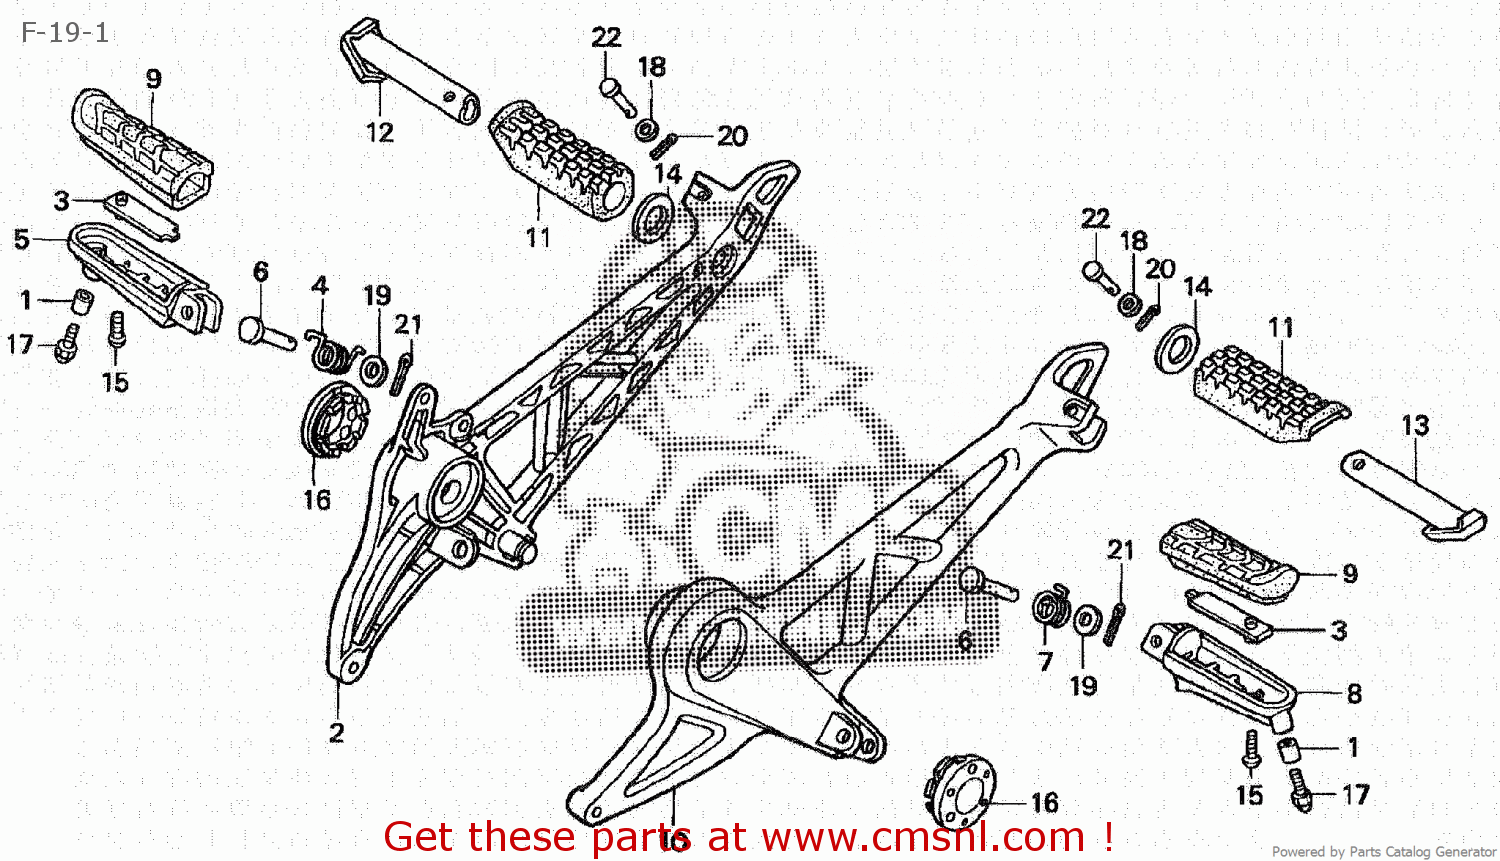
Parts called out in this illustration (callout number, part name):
1	COLLAR SPL.6X22
2	HOLDER,R.STE*NH1*
3	PLATE,STEP SET
4	SPG.,STEP RETURN
5	ARM R,MAIN STEP
6	PIN,STEP BAR
7	SPG,L.STEP RETURN
8	ARM L,MAIN STEP
9	RUBBER,MAIN STEP
10	HOLDER,L.STE*NH1*
11	RUBBER,PILLI STEP
12	BAR,R.PILLI STEP
13	BAR,L.PILLI STEP
14	PLATE,PILLI STEP
15	BOLT,SPECIAL,5X14
16	CAP,PIVOT
17	BOLT,CAP,6X30
18	WASHER,PLAIN, 6MM
19	WASHER,8MM
20	PIN,SPLIT, 1.6
21	PIN,COTTER 2.0X15
22	PIN C,PILLION
